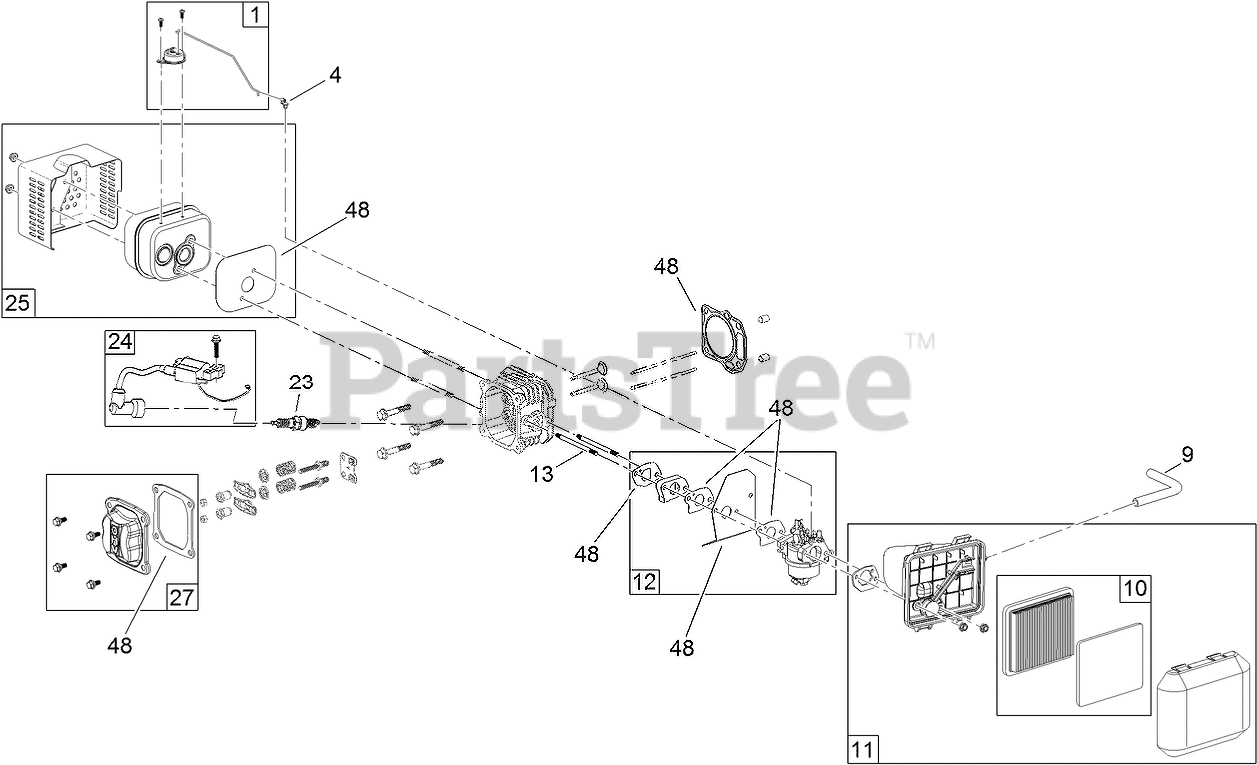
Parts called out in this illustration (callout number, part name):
1	THERMAL CHOKE CONTROL KIT
4	LOCK-THROTTLE
9	TUBE-BREATHER
10	AIR FILTER AND PREFILTER KIT
11	AIR CLEANER ASM
12	CARBURETOR REPAIR KIT
12	CARBURETOR COMPLETE KIT
13	STUD-INTAKE
23	SPARK PLUG
24	IGNITION AND HARDWARE KIT
25	MUFFLER AND SHIELD KIT
27	VALVE COVER KIT
48	SEAL AND GASKET KIT
